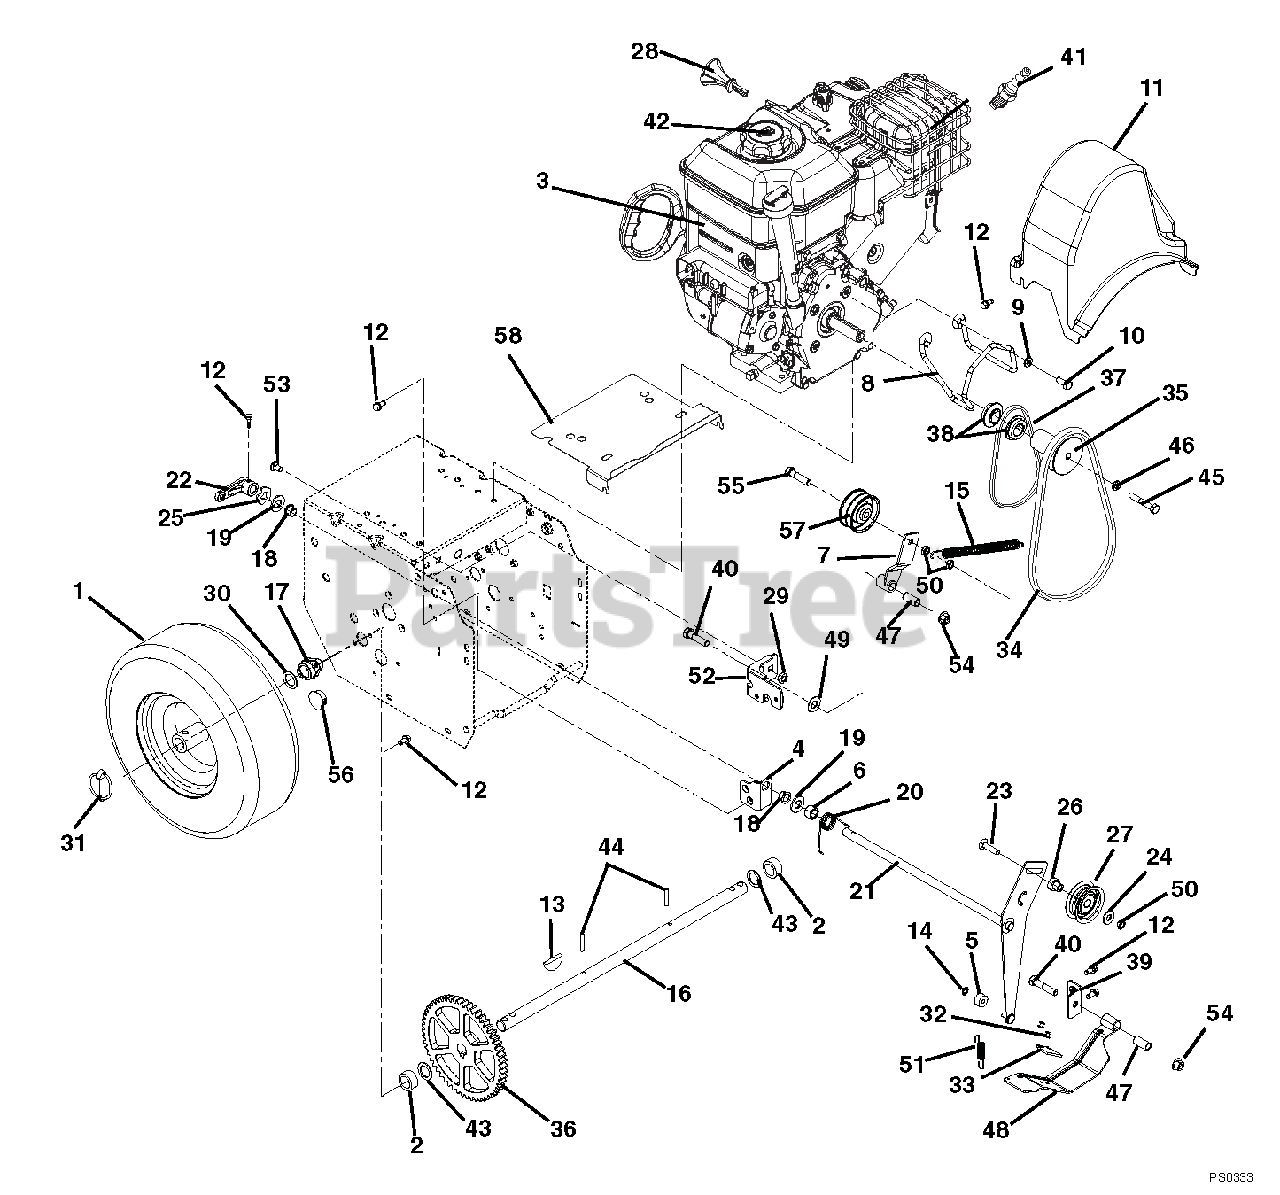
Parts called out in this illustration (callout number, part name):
1	TIRE/WHEEL, RH 4.10-6 PIN K478
1	TIRE/WHEEL, LH 4.10-6 PIN K478
1	TIRE, 4.10-6 K478
2	BSHG-SLV .766 X 1.125 X .500
3	ENGINE, BRIGGS SNOW 900, 120V
3	ENGINE, SUBARU SX17 SNOW 120V
3	ENGINE, BRIGGS SNOW 900,RECOIL
3	ENGINE,SUBARU 6HP SP170 (CARB)
4	BRACKET, MOUNT - IDLER ARM
5	BSHG,SLV .265 X .625 X .375
6	BSHG-SLV .510X.751X.475
7	WELDMENT, TRACTION IDLER ARM
8	FINGER, BELT
8	BELT FINGER
9	WSHR-LK .312X.097 HVY YWZC
10	BLT-HEX .31-24X.75 YWZC GR5
11	COVER, COMPACT BELT
11	PLZ SEE SERVICE LETTER #L-2166
12	SCR-TAP .25-20X.50 HWH TR YWZ
13	KEY-WDRF .25X.750X.313 SAE91
14	RG-RTNG-EXT .250X.010
15	SG-TENS .062X.56X8.0 WLD 11
16	SHAFT, AXLE
17	BSHG .75X1.125X.65
18	BUSHING, POLYLINER-.50 SPLIT
19	@WSHR-FL-STL.531X1.06X.095YWZC
20	SG-TORS .075 X .955
21	WELDMENT, ATTACHMENT IDLER ARM
22	ARM, CLUTCH - ATTACHMENT
23	@BLT-RHDSHSQNK.31-18X1.25 G5YZ
24	@WSHR-FL-STL.38X.875X.083 YWZC
25	WSHR-WAVE .50X.75X.015 .13FRHT
26	SPCR, BRG .315X.50X.688X.281
27	IDLER
28	KEY, PUSH/PULL BRIGGS
28	KEY, PUSH/PULL SUBARU
29	@NUT-LK-TOP-FLG .31-18 YWZC
30	WSHR-FL-STL.754X1.125X.062YWZC
31	PIN-LOK .31X1.75
32	RVT-POP .187 YZ
33	PAD, BRAKE
34	V-BELT, HA-RAW EDGE
35	SHEAVE, AUGER .75ID 920,XXX LG
35	SHEAVE, ATTACHMENT DRIVE
36	SPUR GEAR, 54T .75ID X 6.75PD
37	V-BELT, 3L-WRAPPED
38	TRACTION SHEAVE HALF
39	BRACKET, MOUNT - BRAKE
40	@BLT-HEX .38-16X1.75 GR5 YWZC
41	PLUG, SPARK
41	PLUG, SPARK SUBARU
42	CAP, FUEL - BRIGGS & STRATTON
42	CAP, FUEL SUBARU
43	WSHR-FL-STL.754X1.125X.062YWZC
44	PIN-ROLL .188X1.25
45	@BLT-HEX .31-24X1.75 GR5 YWZC
45	BLT-HEX .31-24X2.00 GR5
46	WSHR-LK .312X.097 HVY YWZC
47	BSHG-SLV .385X.500X1.045
48	BRAKE ARM W/PAD
49	@WSHR-FL-STL.406X.812X.065 YWZ
50	@NUT-LK-CTR-JAM .31-18 YWZC
51	SPRING-EXT .437 X .438 X 2.64
52	WELDMENT, FRAME BRACKET
53	@BLT-RHDSSQNK .31-18X.62 G5YZ
54	@NUT-LK-TOP-FLG .38-16 YWZC
55	@BLT-HEX .31-18X1.50 GR5 YWZC
56	PLUG, HOLE - 1.00" FLEXTEMP
57	IDLER,1.875" OD
58	BAFFLE,ENGINE,SMALL BLOCK
